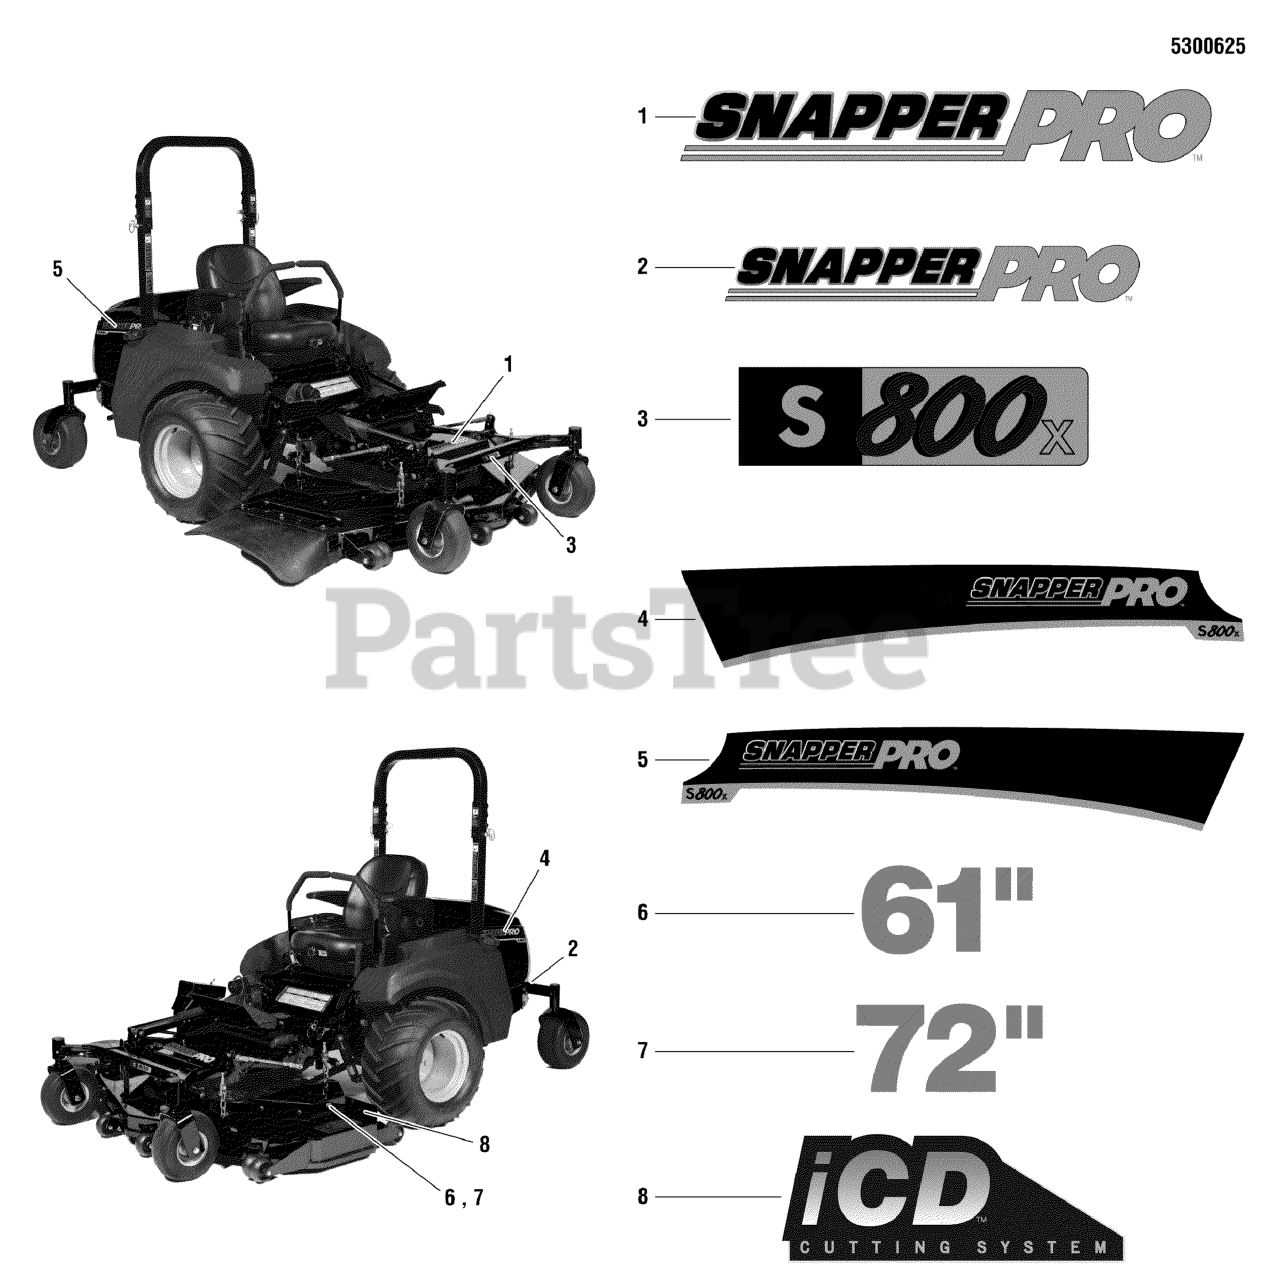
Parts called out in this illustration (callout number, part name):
1	DECAL, SNAPPER PRO, FRONT
2	DECAL, FRONT, SNAPPER PRO
3	DECAL, S800X
4	DECAL, LH STRIPE, S800X
5	DECAL, RH STRIPE, S800X
6	DECAL, 61
7	DECAL, 72
8	DECAL, iCD CUTTING SYSTEM
